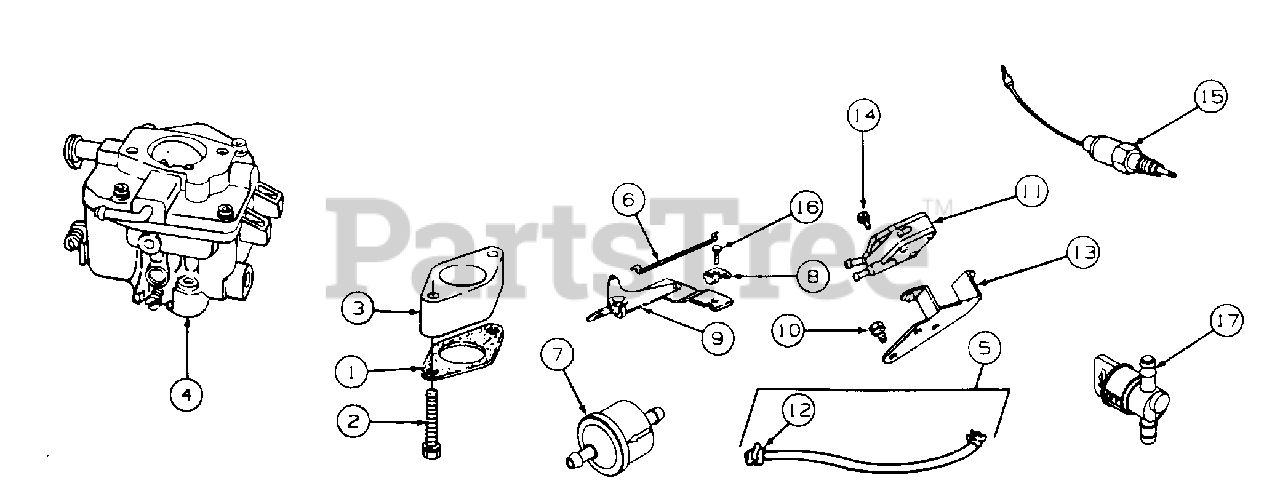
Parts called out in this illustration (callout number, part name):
1	Gasket, Carburetor Mtg
2	Screw, Sems
3	Spacer, Carburetor
4	Carburetor Assy
5	Line, Fuel
6	Link, Choke
7	Filter, Fuel
8	Clamp, Casing
9	Bracket, Choke
10	Screw, Sems
11	Pump, Fuel
12	Clamp, Fuel Line
13	Bracket, Fuel Pump
14	Screw, Mtg
15	Solenoid
16	Screw, Hex Hd
17	Valve, Shutoff
